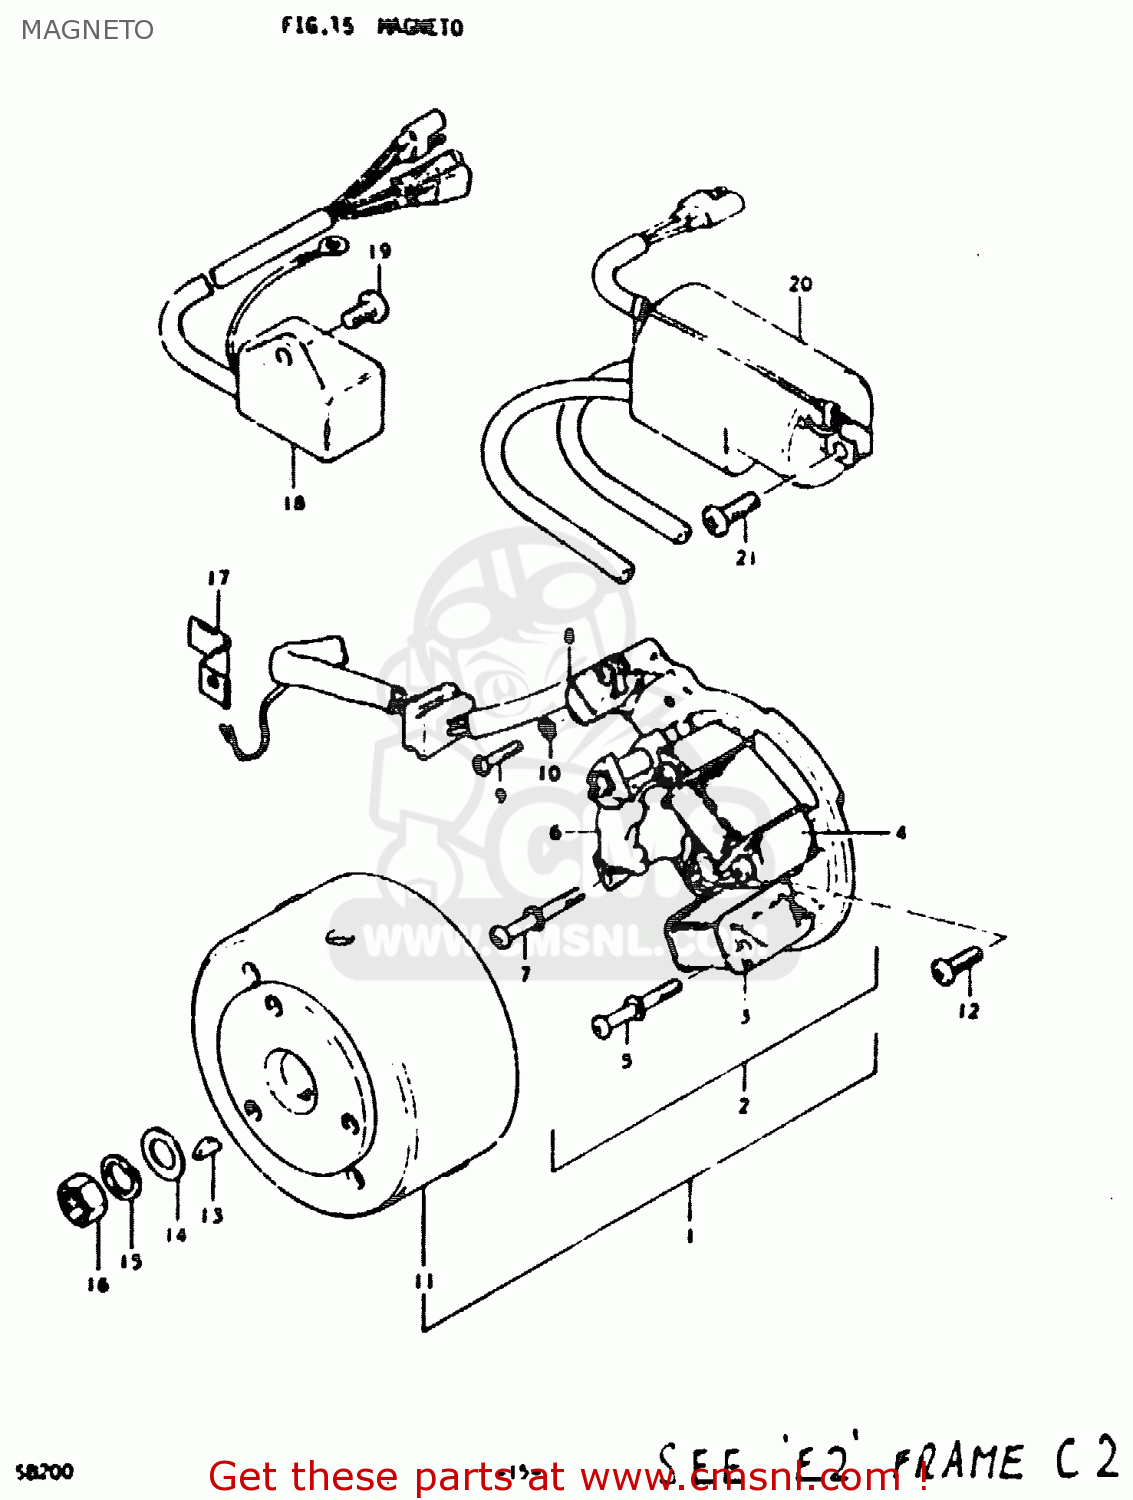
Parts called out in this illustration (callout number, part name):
1	MAGNETO ASSY
2	STATOR ASSY
3	COIL,LIGHTING(A)
4	COIL, LIGHTING B
5	SCREW
6	COIL, PRINAR,
7	SCREW
8	COIL,PULSER
9	SCREW
10	LOCK WASHER
11	ROTCH
12	SCREW
13	KEY
14	WASHER
15	WASHER,LOCK 12
16	NUT
17	CLAMP
18	C.D.I. UNIT ASSY
19	SCREW 6X12
20	COIL ASSY, IGNITION
21	SCREW
